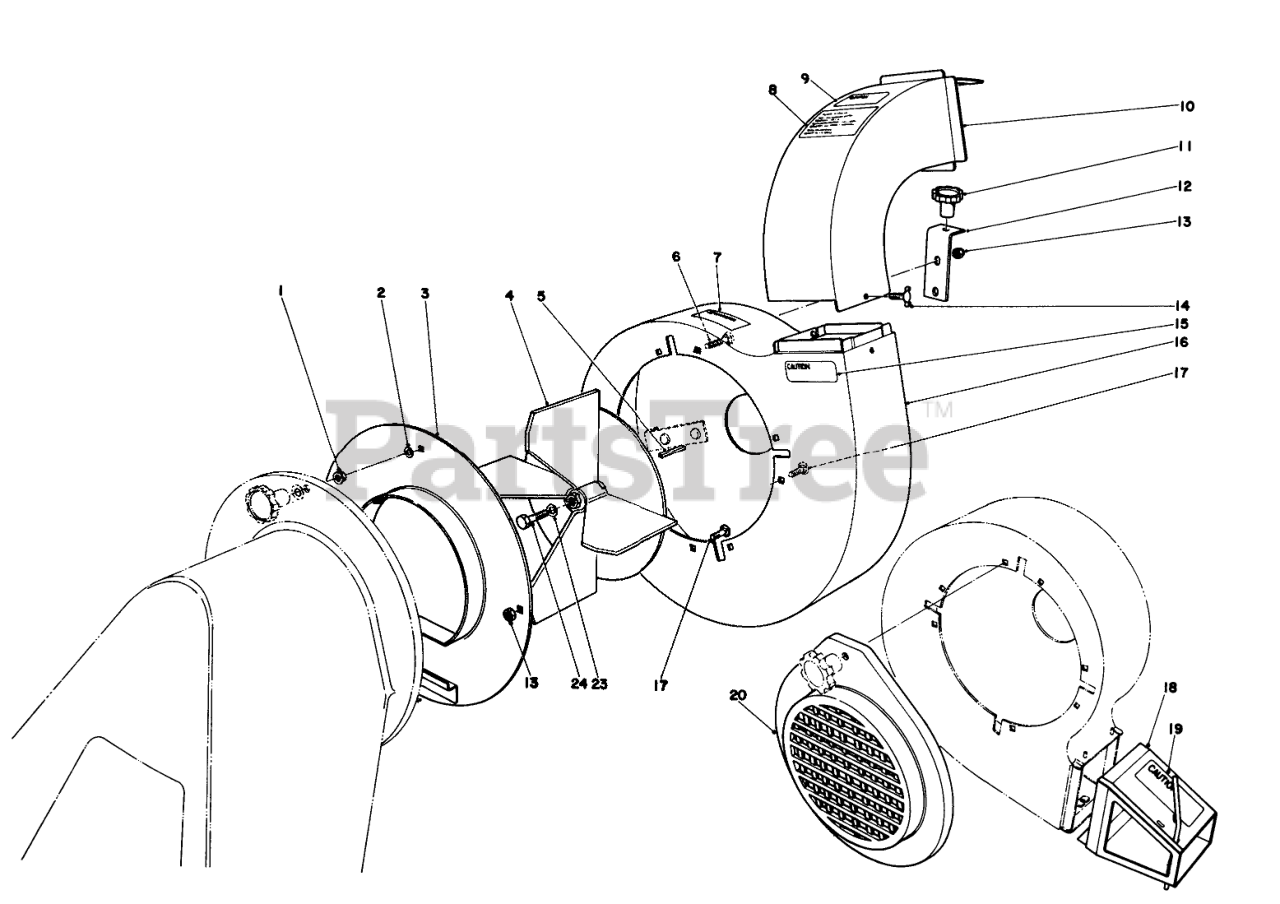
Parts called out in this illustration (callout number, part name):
1	NUT-FLANGE
2	WASHER-FLAT
3	Blower Cover
4	Fan
5	KEY-SQUARE
6	SCREW-CARR
7	ROTATE WARNING DECAL
8	TORO ADVER DECAL
9	DECAL CAUTION BAG
10	Chute-Vacuum
12	Bracket-Housing
13	NUT-LOCK, CONE
14	1/4 - 20 3/4 WING SCR
15	WARNING DECAL
16	Blower Housing
17	SCREW-CARR
18	Blower Exhaust (Incl. Ref. #19)
19	EXHAUST DECAL
20	INTAKE-BLOWER
23	WASHER-LOCK
24	SPEC SCREW
